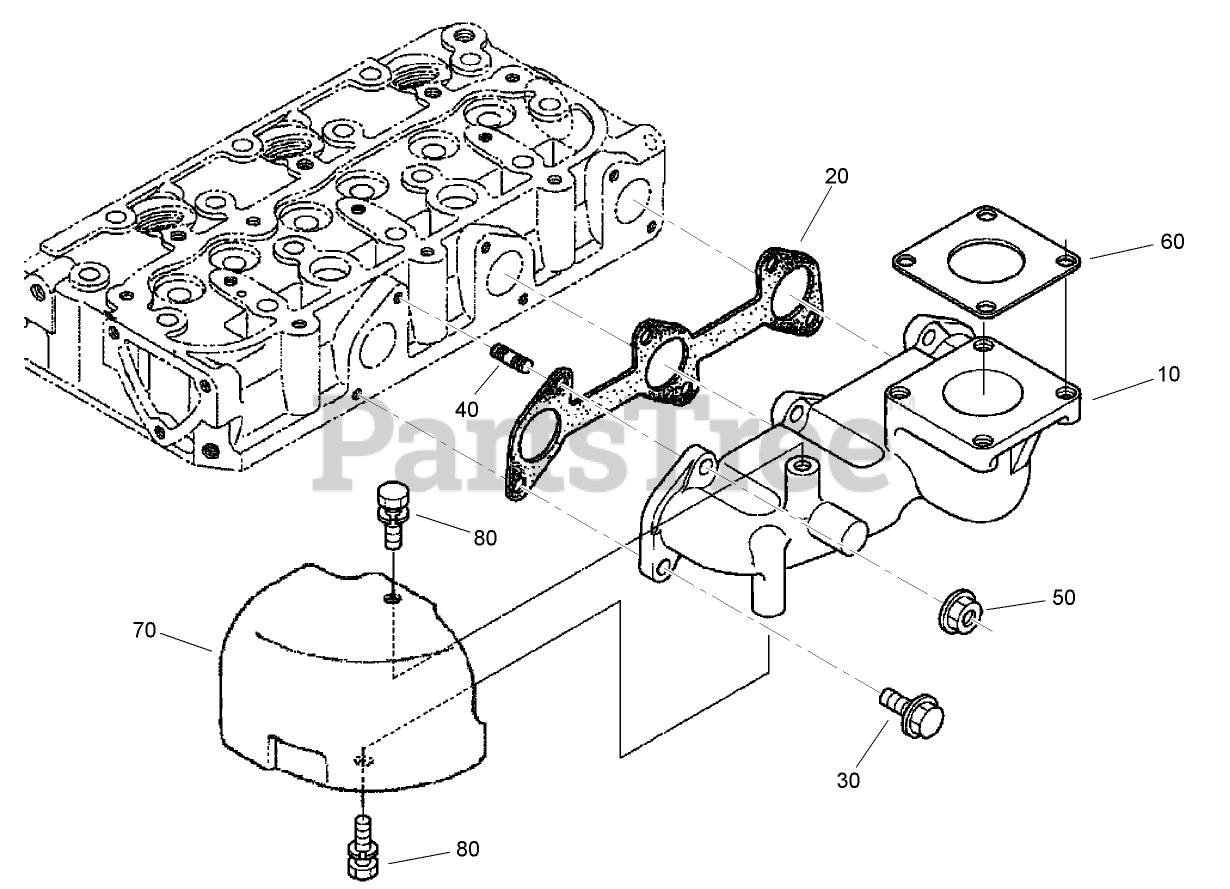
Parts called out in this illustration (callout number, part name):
10	MANIFOLD-EXHAUST
20	GASKET-MANIFOLD, EXHAUST
40	Bolt-Flange
60	GASKET-MUFFLER
70	COVER-HEAT
80	BOLT
